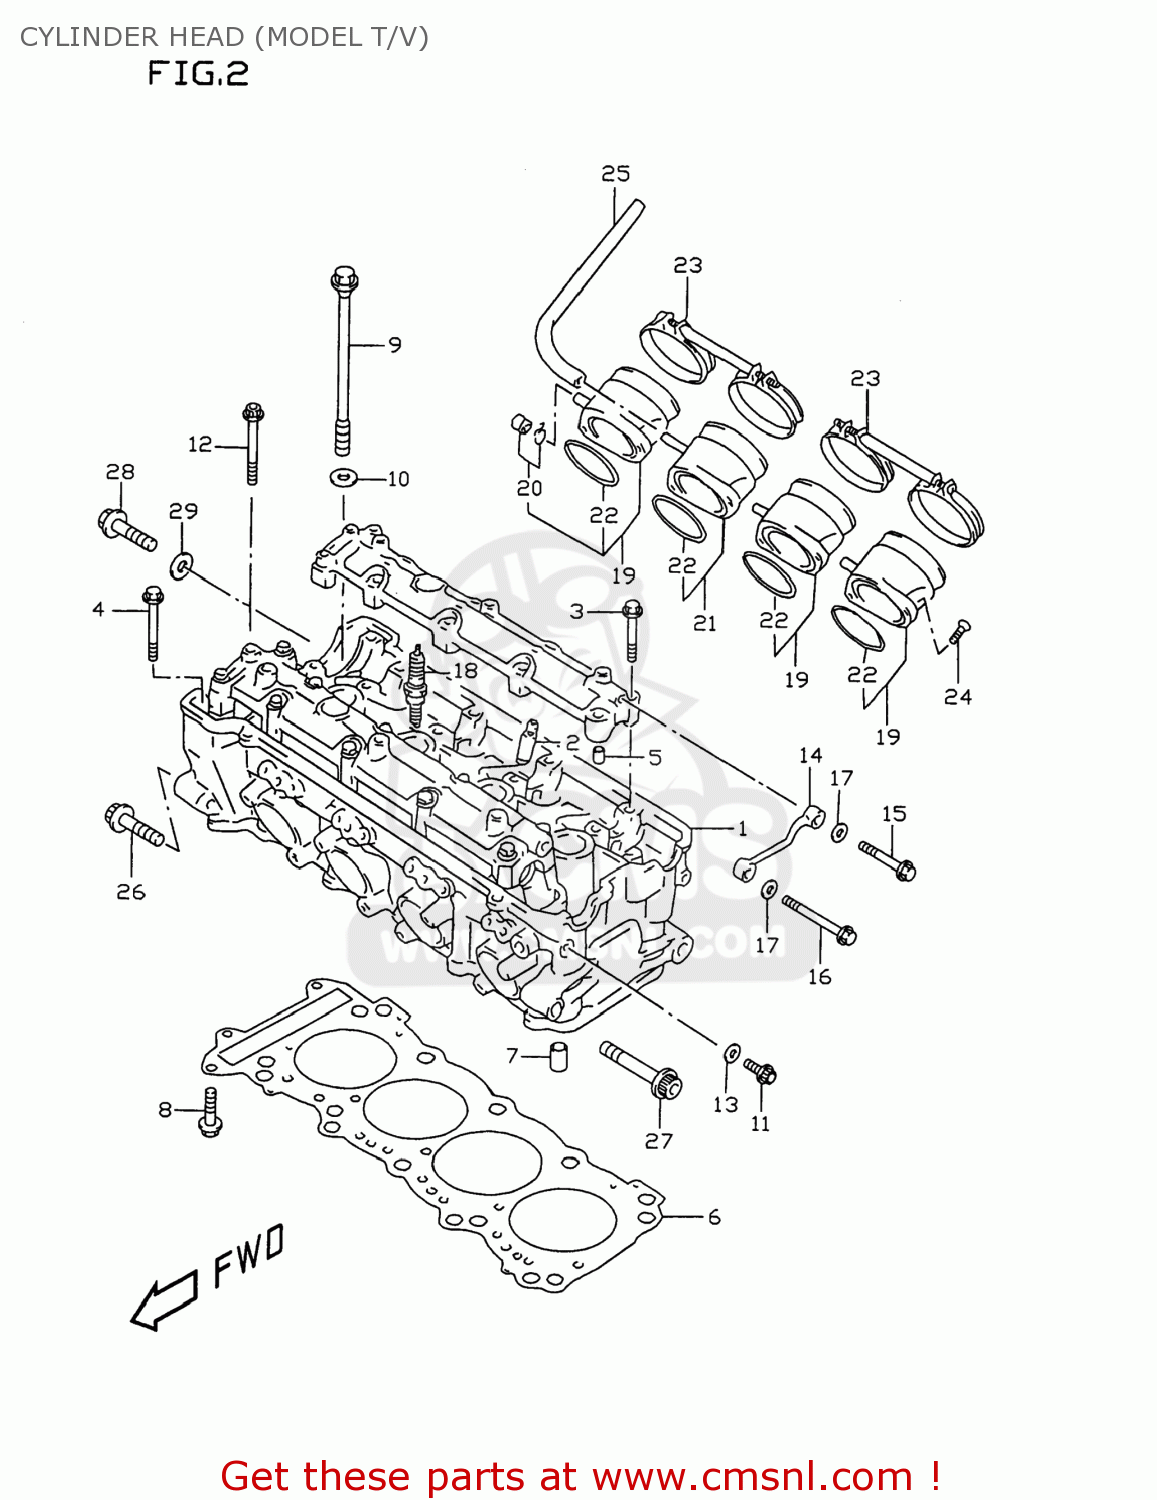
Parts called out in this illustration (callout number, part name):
1	HEAD ASSEMBLY,CYLINDER
2	GUIDE,VALVE
3	BOLT(6X39)
4	BOLT(6X45)
5	PIN(6.2X8X16)
6	GASKET,CYLINDER HEAD (T
7	PIN
8	BOLT
9	BOLT(10X160)
10	WASHER(10.5X19X2)
11	BOLT
12	BOLT,CYL.OIL P
13	GASKET(5.8X13X1.2) (NAS)
14	PIPE,CYLINDER HEAD OIL
15	BOLT
16	BOLT (6X45)
17	WASHER
18	PLUG,SPARK(CR8E)
19	PIPE ASSY,INTAKE
20	CAP
21	PIPE ASSY,INTAKE NO.3
22	O RING(D:2.4,ID:44)
23	CLAMP,INTAKE PIPE
24	SCREW
25	HOSE(5X10X600)
26	BOLT
27	BOLT
28	BOLT,CYL HEAD SIDE FACE
29	WASHER,HEAD COVER
